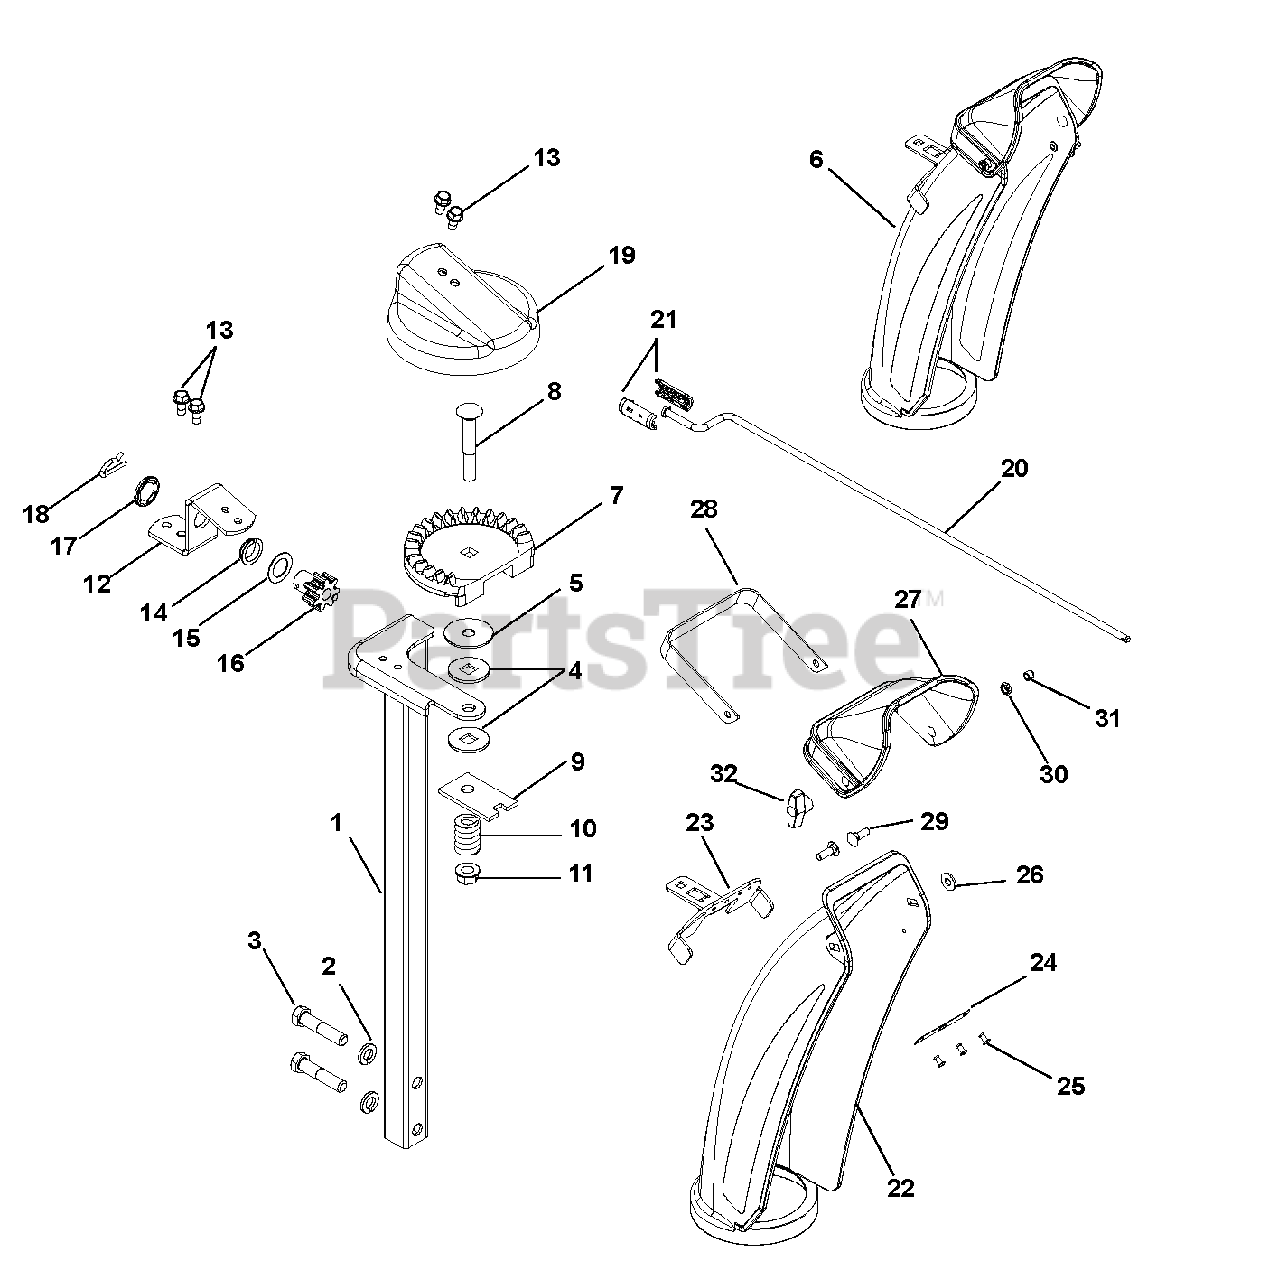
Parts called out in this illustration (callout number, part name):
1	CHUTE PEDESTAL, TALL COMPACT
2	@WSHR-LK .38X.094 REG YWZC
3	@BLT-HEX .38-16X1.75 GR5 YWZC
4	FRICTION WASHER
5	@WSHR-FL-STL .406X1.25X.10 ZC
6	CHUTE, MANUAL DISCHARGE W/CAP
7	CHUTE GEAR
8	@BLT-RDHDSQNK .38-16X2.50 G5YZ
9	PLATE, FRICTION
10	SG-COMP .187X.56X1.62
11	@NUT-LK-TOP-FLG .38-16 YWZC
12	BRACKET, PINION GEAR
13	SCR-TAP .25-20X.50 HWH TR YWZ
14	BUSHING, POLYLINER-.63 SNAPIN
15	WSHR-THRST .625 X 1.0 X .03
16	PINION GEAR W/BRACKET
17	PUSHNUT .625
18	PIN, SPRING CLIP
19	GEAR COVER
20	ROD, CHUTE CRANK - SINGLE SPD
21	KNOB, CHUTE CRANK - SNAP BLK
22	CHUTE, PLASTIC DISCHARGE LONG
23	CHUTE MOUNT BRACKET
24	PLATE,CHUTE MOUNT BACKING
25	RIVET, #66 STEEL POP PD BLACK
26	@WSHR-FL-STL.38X.875X.083 YWZC
27	DEFLECTOR CAP, PLASTIC
28	HANDLE, MANUAL CHUTE CAP
29	BLT,RNHDRECSHNK .31-18X1.00
30	@NUT-LK-CTR-JAM .31-18 YWZC
31	CAP, END .281X.313
32	KNOB, WING .31-18 UNC
